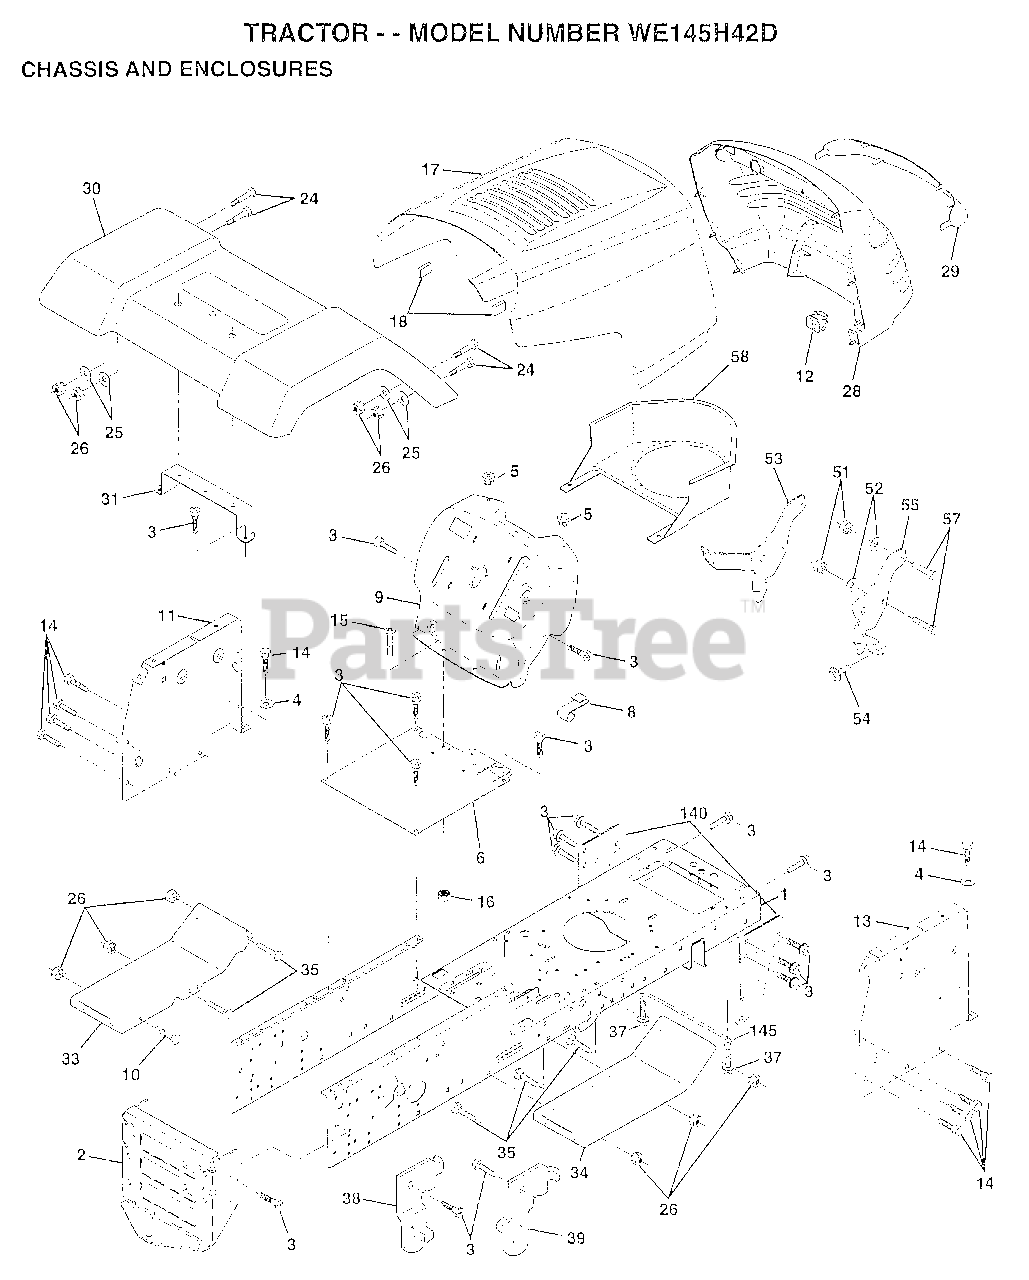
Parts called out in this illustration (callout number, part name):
3	SCREW
4	WASHER
5	BUMPER-HOOD/DASH
6	SADDLE
8	CLIP.RETAINER
9	DASH SILKSCREEN
11	"PANEL-DASH,LH"
12	CLIP.TINNERMAN
14	SCREW LT
15	SCREW
17	HOOD.STEEL.ASSY
24	BOLT
25	WASHER
26	NUT
28	GRILLE-MS428
29	LENS GRILLE
31	BRKT FENDER
33	FOOTREST.LH.PERF.
34	FOOTREST.RH.PERF.
35	BOLT
38	BRACKET ASM LH
39	BRACKET ASM RH
51	NUT
52	WASHER
53	BRACKET.GRILLE.LH
54	SCREW.HEX.WS.HD
55	BRACKET.GRILLE.RH
58	AIR DUCT
140	BRKT SUSPENSION
145	"ROD POVOT,CHASSIS"
